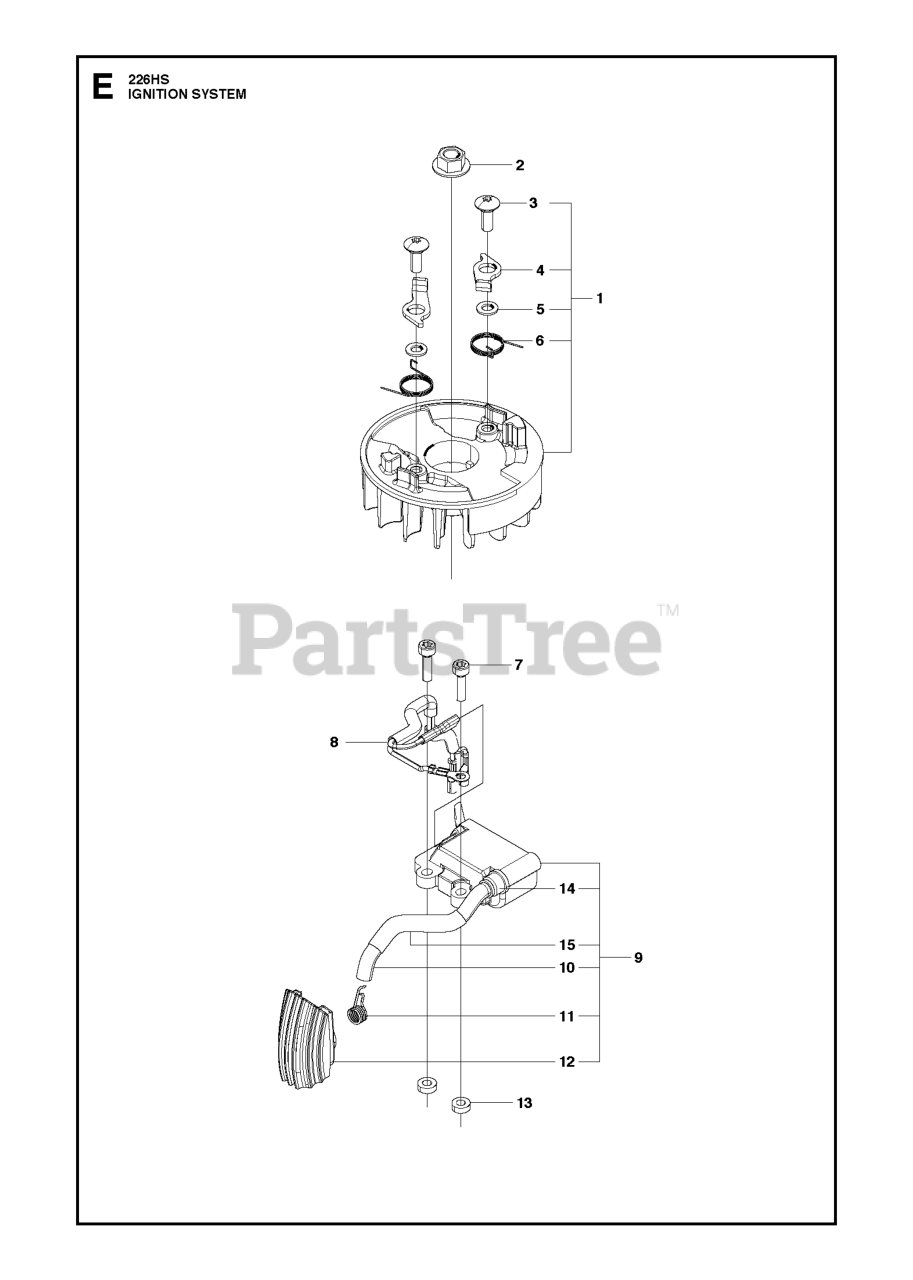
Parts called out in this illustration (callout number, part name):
1	ROTOR ASSY
2	NUT
5	WASHER 5X10X10
14	CAP
